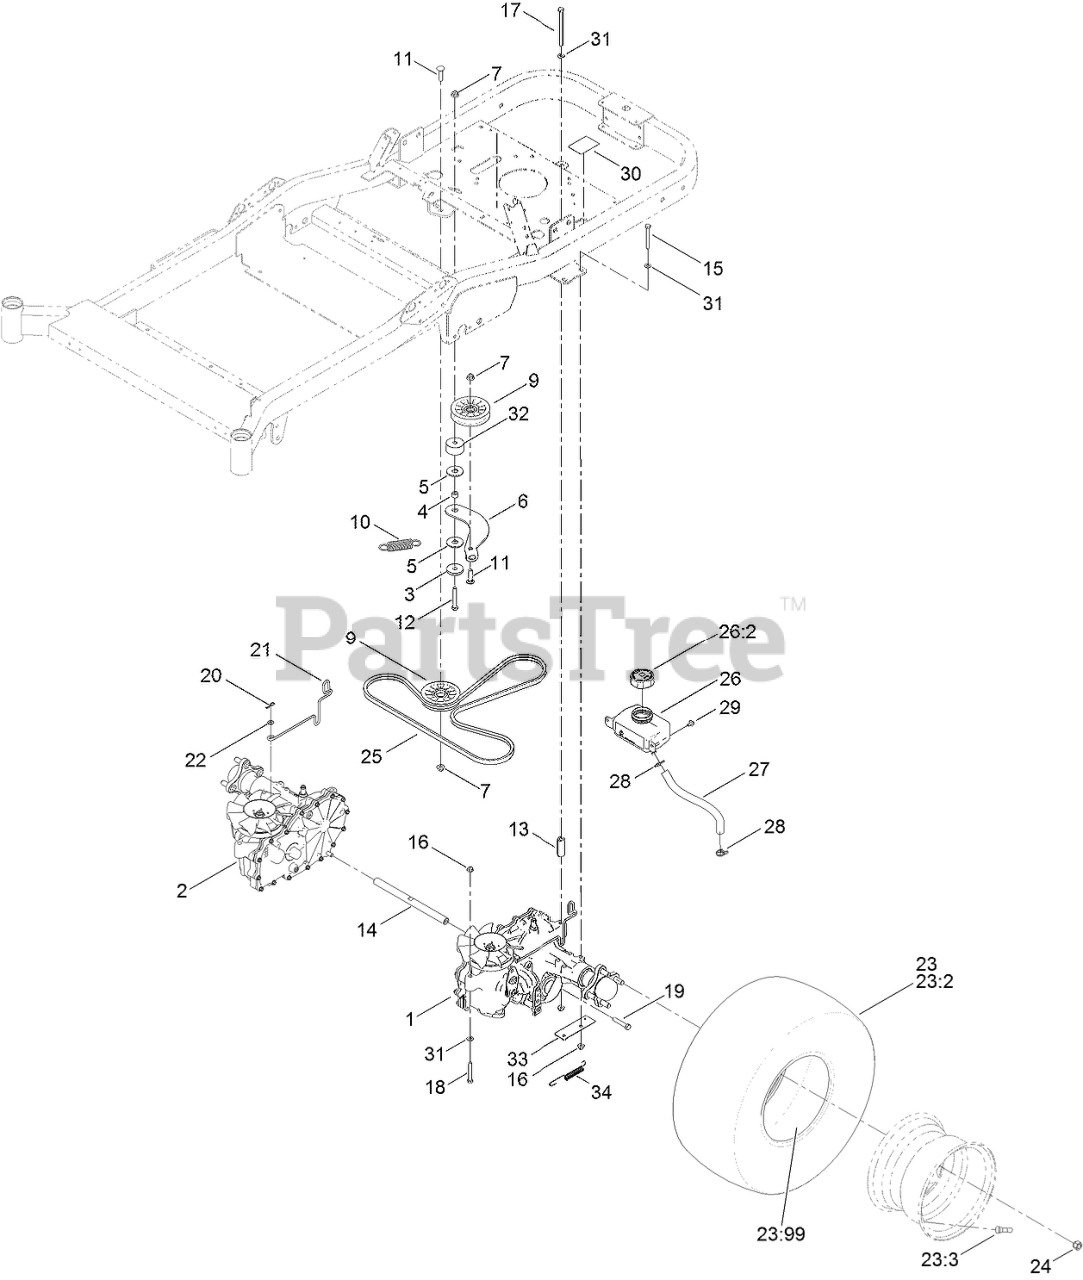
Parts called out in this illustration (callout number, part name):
1	LH HYDRO TRANSMISSION ASM
2	RH HYDRO TRANSMISSION ASM
3	WASHER-PLAIN
4	SPACER
5	WASHER-FRICTION, COMPOSITE
6	ARM-IDLER
7	NUT-HF, NI
9	PULLEY-IDLER, FLAT
10	SPRING-EXTENSION
11	SCREW-CARR
12	SCREW-HH
13	SPACER-HYDRO
14	SHAFT-CROSS, HYDRO
15	SCREW-HH
16	NUT-HF, NI
17	SCREW-HH
18	SCREW-HH
19	SCREW-HH
20	PIN-COTTER
21	ROD-BYPASS
22	WASHER
23	TIRE AND WHEEL ASM
23:3	STEM-VALVE
23:99	Tube-Inner
24	NUT-LUG
25	V-BELT
26	HYD RESERVIOR ASM
26:2	CAP-RESERVOIR, HYD
27	HOSE-OVERFLOW
28	CLAMP-HOSE
29	SCREW-HHFTF
30	DECAL-BYPASS
31	WASHER-PLAIN
32	SPACER
33	PLATE-SPRING
34	SPRING-EXTENSION
